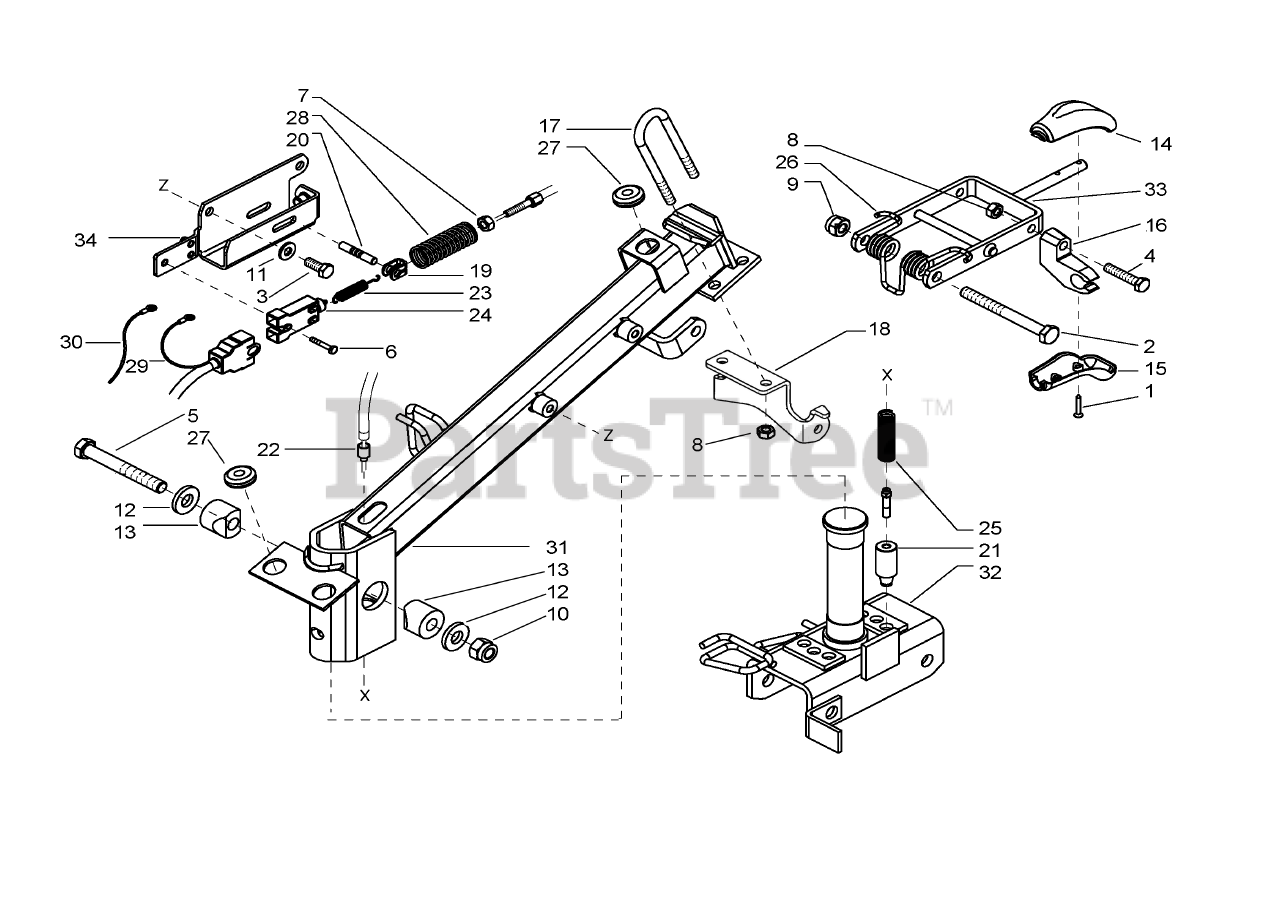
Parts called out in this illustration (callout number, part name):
1	SCREW, M5X25
2	CAP SCREW, M10X110 UNI 5737-8G
3	CAP SCREW, M8X20 UNI 5739-8G
4	CAP SCREW,
5	CAP SCREW, M12X80
6	CAP SCREW
7	NUT, M8
8	NUT, SELF LOCKING, M8
9	NUT, LOCK STANDARD, M10
10	NUT, LOCK DEFORMED, M12
11	WASHER, SUPER, M8
12	WASHER, SPRING
13	WEDGE
14	KNOB, UPPER HANDLE RELEASE
15	KNOB, LOWER HANDLE RELEASE
16	SUPPORT, CONTROL ROD
17	U-BOLT
18	BRACKET
19	MOTOR STOP FORK
20	M/S SPRING CHECK PIN
22	SHEATH END
23	SPRING
24	INTERLOCK SAFETY
25	SPRING, STEERING COLUMN
26	SPRING, HANDLEBAR RELEASE
27	SUPPORT, CAP
28	CHECK SPRING, MOTOR STOP
29	WIRE HARNESS, MOTOR STOP
30	GROUND WIRE
31	STEERING COLUMN
32	STEERING COUPLER
33	LEVER, HANDLE BAR
34	SUPPORT, ENGINE STOP
